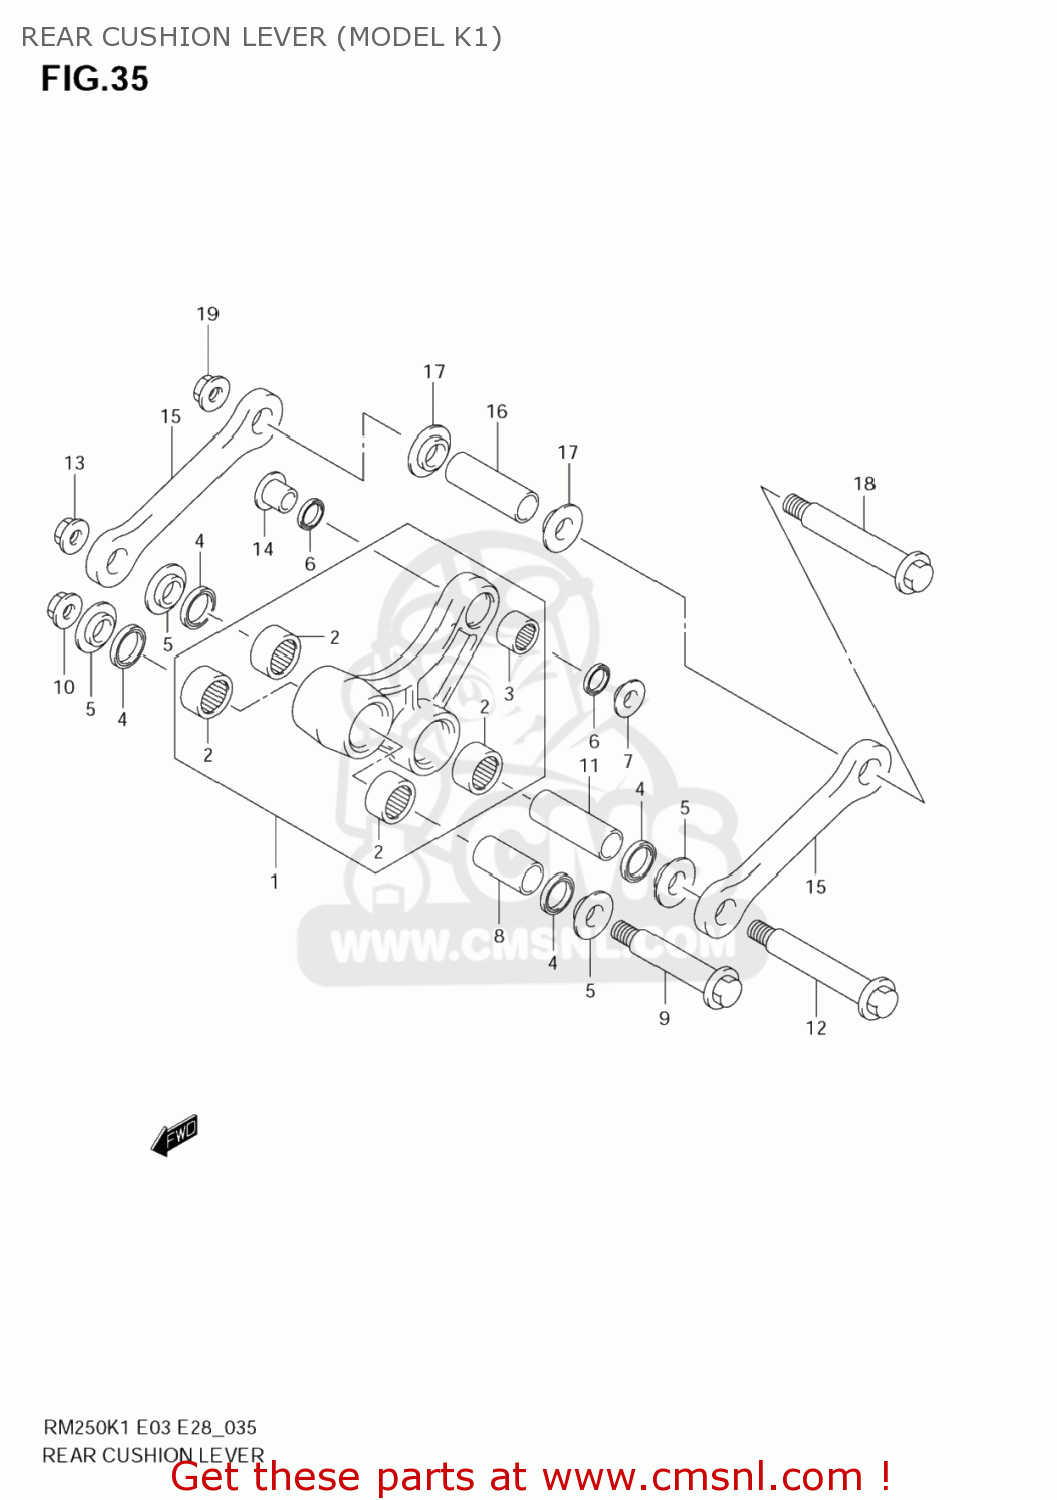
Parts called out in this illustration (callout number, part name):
1	LEVER SET,REAR
2	BEARING(20X27X15)
3	BEARING(16X22X12)
4	SEAL,CUSHION LEVER DUST
5	SPACER,RR CUSH ROD SIDE
6	SEAL,OIL(16X22X2.5)
7	SPACER,RR CUSHION LEVER RR,L
8	SPACER,RR CUSHION LEVER FR
9	BOLT,RR CUSHION LEVER FR
10	NUT
11	SPACER,RR CUSHION
12	BOLT,RR CUSHION
13	NUT
14	SPACER,RR CUSHION LEVER RR,R
15	ROD,RR CUSHION
16	SPACER,RR CUSHION
17	SPACER,RR CUSH ROD SIDE
18	BOLT,RR CUSHION
19	NUT
